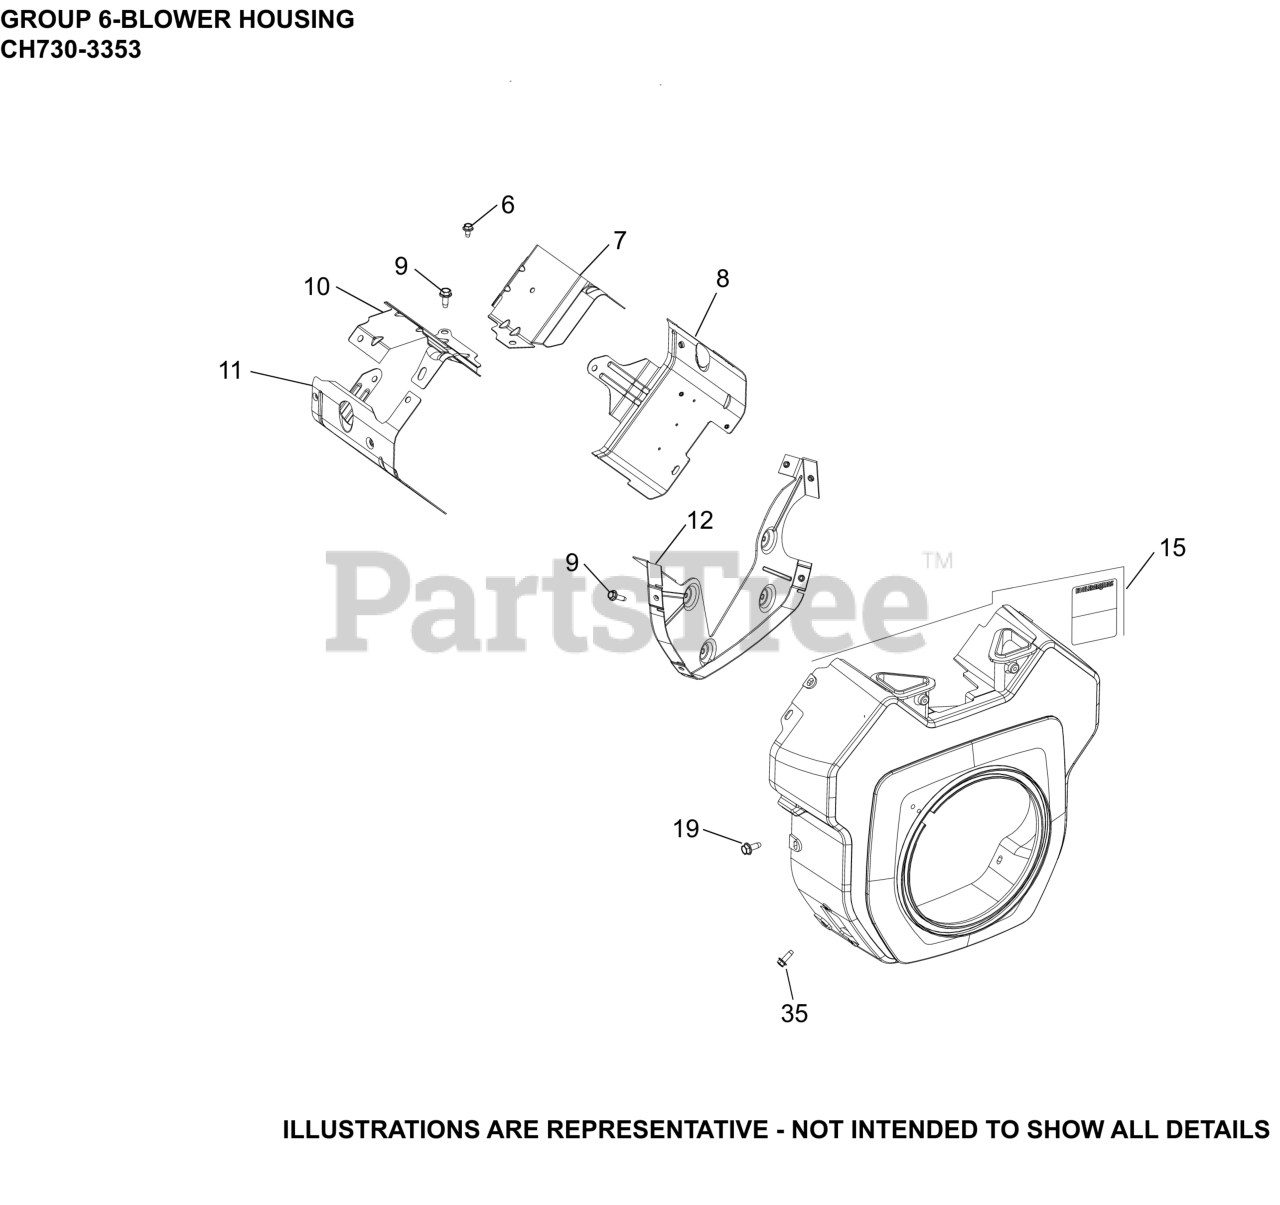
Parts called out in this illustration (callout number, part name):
6	SCREW, THREAD FORMING
7	BAFFLE, VALLEY #1 CYLINDER
8	KIT, CYL BAFFEL #1 SIDE
9	SCREW, THREAD FORMING
10	BAFFLE, VALLEY #2 CYLINDER
11	BAFFLE, LEFT BARREL
12	KIT, BACKING PLATE
15	HOUSING, BLOWER
15	KIT, BLOWER HOUSING
19	SCREW, THREAD FORMING
35	SCREW, THREAD FORMING
